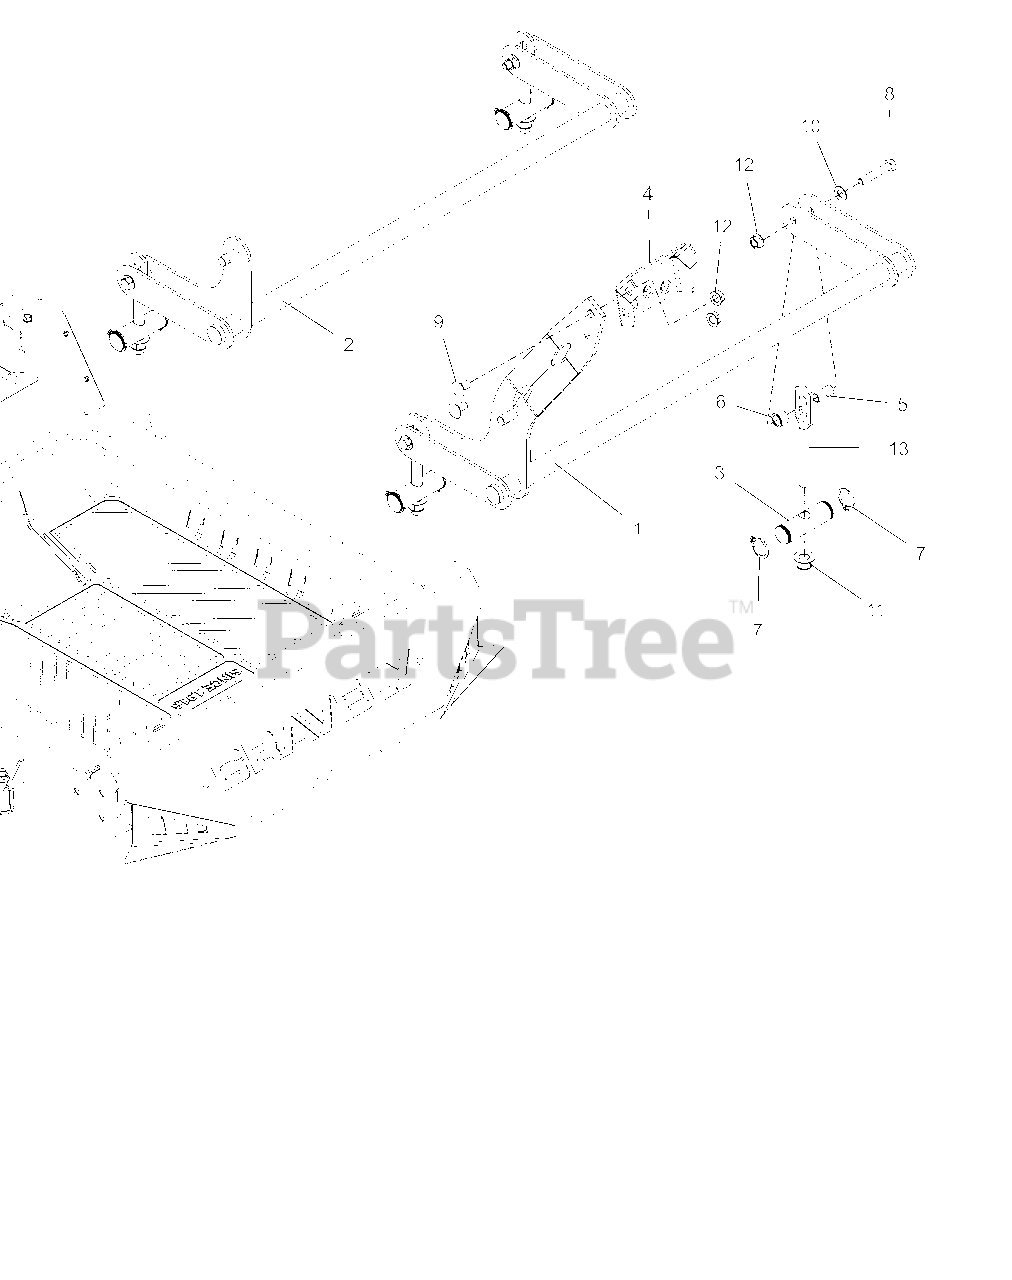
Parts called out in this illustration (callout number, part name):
1	WLDMT, FRONT DECK LIFT PIVOT
2	WLDMT, REAR DECK PIVOT
3	SHAFT, DECK LINK PIVOT
4	PEDAL, DECK LIFT (BOLT ON)
5	BSHG-SLV .385X.500X1.045
6	BSHG-SLV .510X.751X.475
7	RG-RTNG-EXT 1.00X.078
8	BLT-HEX .38-16X2.00 GR8 YWZC
9	BLT,RHSN .38-16X.75 G5 BFP
10	@WSHR-FL-STL.406X.812X.065 YWZ
11	@NUT-LK-NYL-FLG .50-13 YWZC
12	NUT-LK-CTR-FLG .38-16 YWZC
13	LINK, DECK (LONGER)
